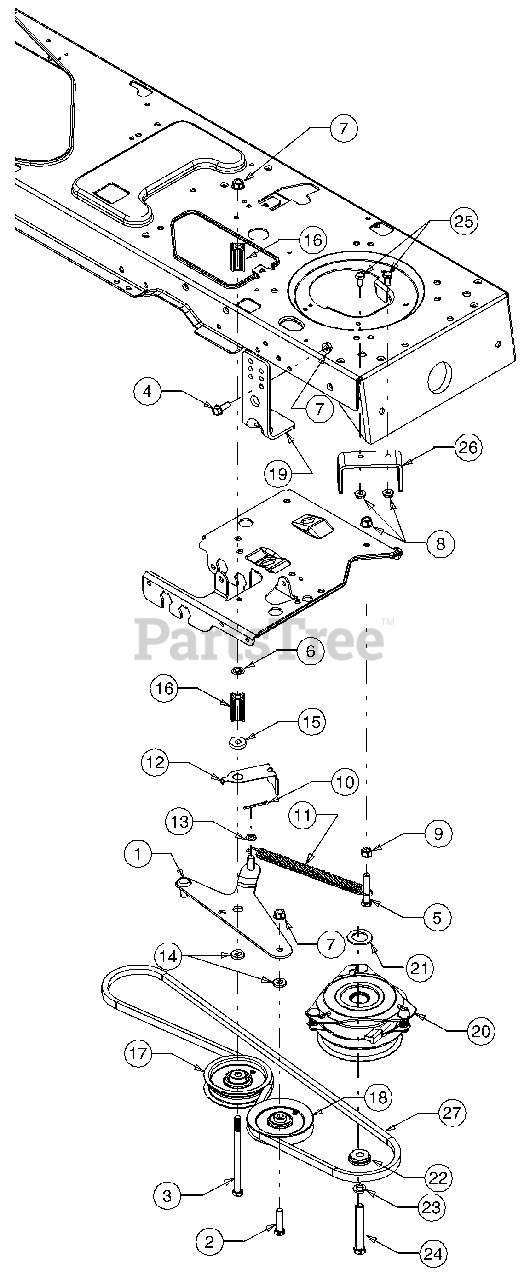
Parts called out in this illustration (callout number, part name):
3	Screw, 3/8-16, 5.5 (Model 1517)
4	Screw, 5/16-18, .875
5	Screw, 3/8-16, 2.0 (Model 1517)
6	Push Nut, 3/8 (Model 1517)
7	Nut, Flange Lock, 3/8-16
8	Nut, Flange Lock, 5/16-18
9	Nut, 3/8-16 (Model 1517)
10	Cotter Pin, 1/8 x 1.25 (Model 1517)
11	Spring, Extension .62 x 6.12 (Model 1517)
12	Belt Guard (Model 1517)
13	Washer, Flat .385 x .62 x .063 (Model 1517)
14	Washer, Flat .407 x .812 x .135 (Model 1517)
15	Shoulder Spacer, .380
16	Spacer, 3/8 x 1.54
17	Pulley, Idler, 3.5 (Model 1517)
18	Pulley, Idler, 4.0 (Model 1517)
20	Clutch, Electric PTO, 6" (Model 1515)
21	Washer, Flat, 1.031 x 1.620 x .095
22	Spacer, Shoulder, 1.38 x .445 x .36
23	Washer, Lock, 7/16, Regular Duty
24	Screw, 7/16-20, 3.25, Gr5
25	Screw, 5/16-18, .625, Gr5
